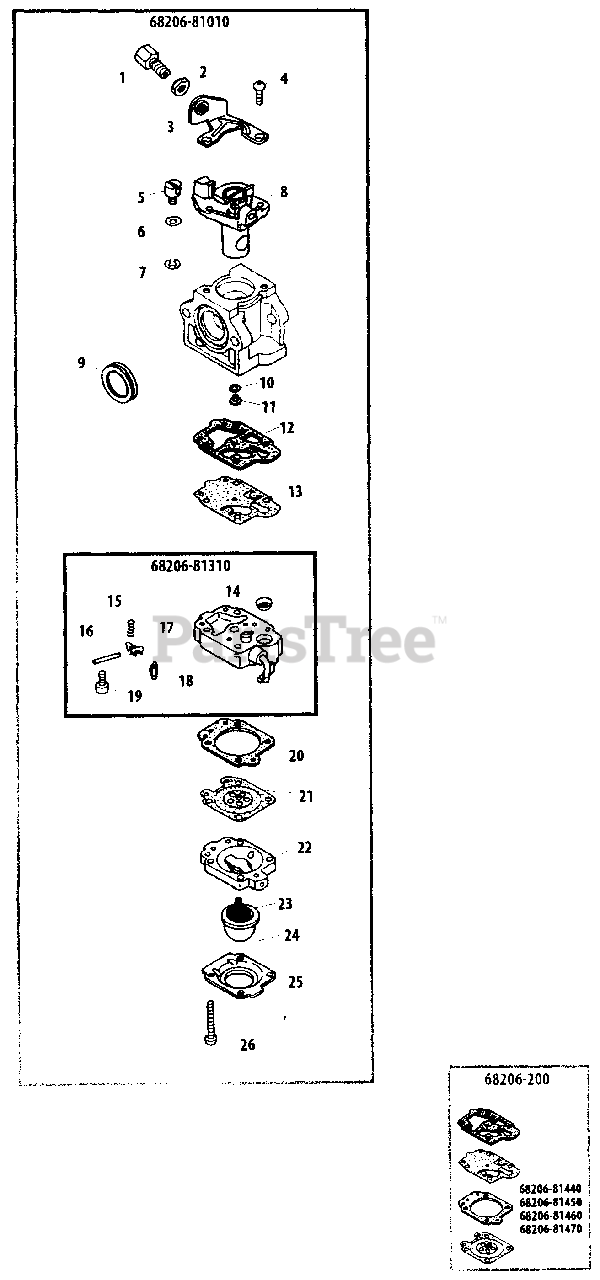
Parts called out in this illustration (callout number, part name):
1	NUT, CABLE ADJUST
3	BRACKET, CABLE
7	RING, RETAINING
9	SEAL
11	JET, MAIN
12	GASKET, PUMP
13	DIAPHRAGM, PUMP
14	STRAINER
15	SPRING, METERING LEVER
16	PIN, METERING LEVER
17	LEVER, METERING
18	VALVE, NEEDLE
19	SCREW, METERING LEVER PIN
20	GASKET, METERING
21	DIAPHRAGM, METERING
22	BASE, PURGE
23	VALVE, CHECK
24	BULB, PURGE
25	COVER, PUMP
68206-200	DIAPHRAGM/GASKET KIT
68206-81010	CARBURETOR
68206-81310	BASE, PURGE
